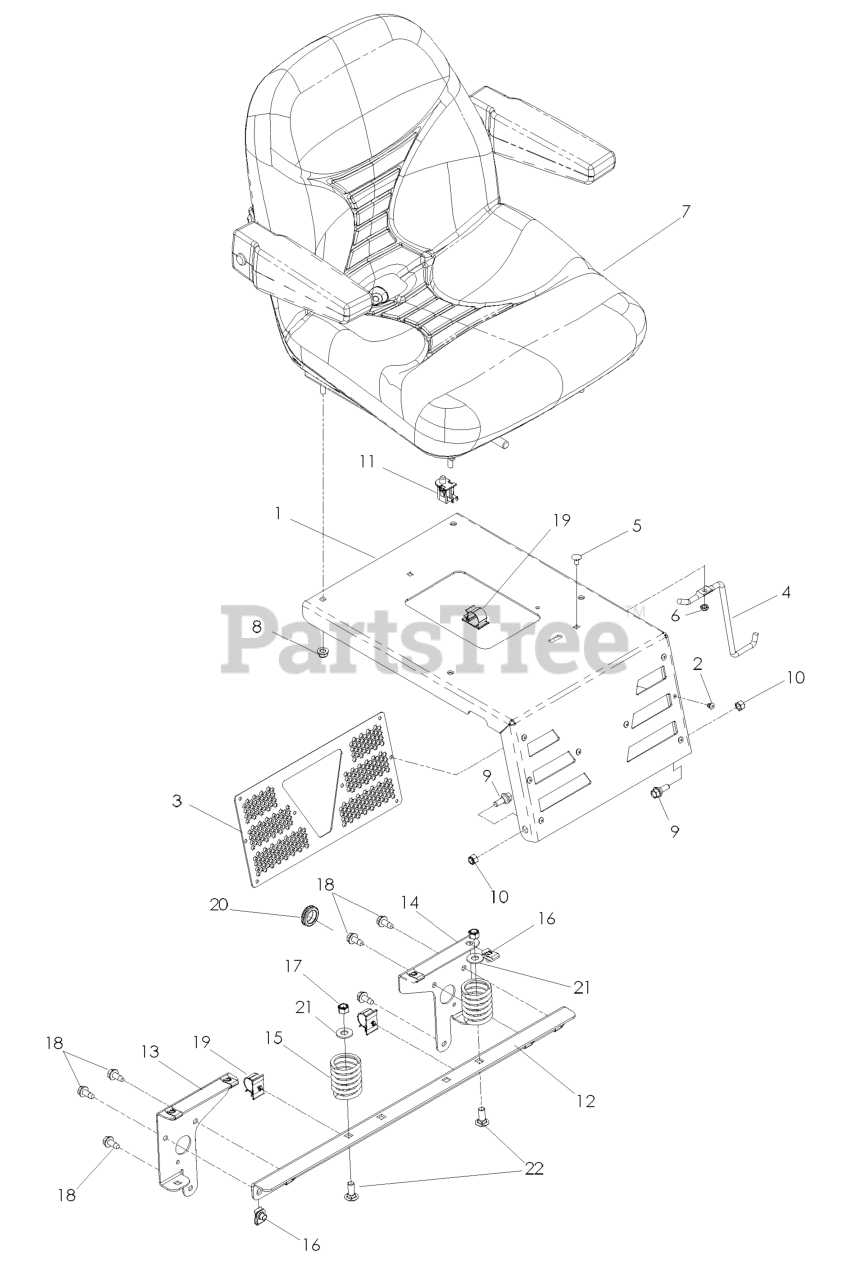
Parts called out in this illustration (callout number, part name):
1	SEAT MOUNT W/DECAL
2	RIVET, 3/16" - .06-.25 GRIP
3	PANEL, HEX
4	STOP, SEAT, FORWQARD
5	RHSSNB 1/4-20 X 1/2
6	JAM NUT 1/4C (2 2 PW01)
7	SEAT
8	5/16-18 NYLOC FLANGE NUT
9	SB 5/16-18 HEX HD GD5, BLK ZN
10	NUT 5/16 NYLOC
11	SEAT SWITCH
12	SUPPORT, SEAT
13	SUPPORT, LT
14	SUPPORT, RT
15	SPRING, SEAT
16	U-CLIP 5/16-18 NUT RETAINER
17	NUT 3/8-16 NYLOC
18	BOLT 5/16-18 X 3/4
19	PUSH-MOUNT WIRE CLIP
20	RUBBER GROMMET
21	WASHER 3/8 FLAT
22	RHSNB 3/8C X 1
